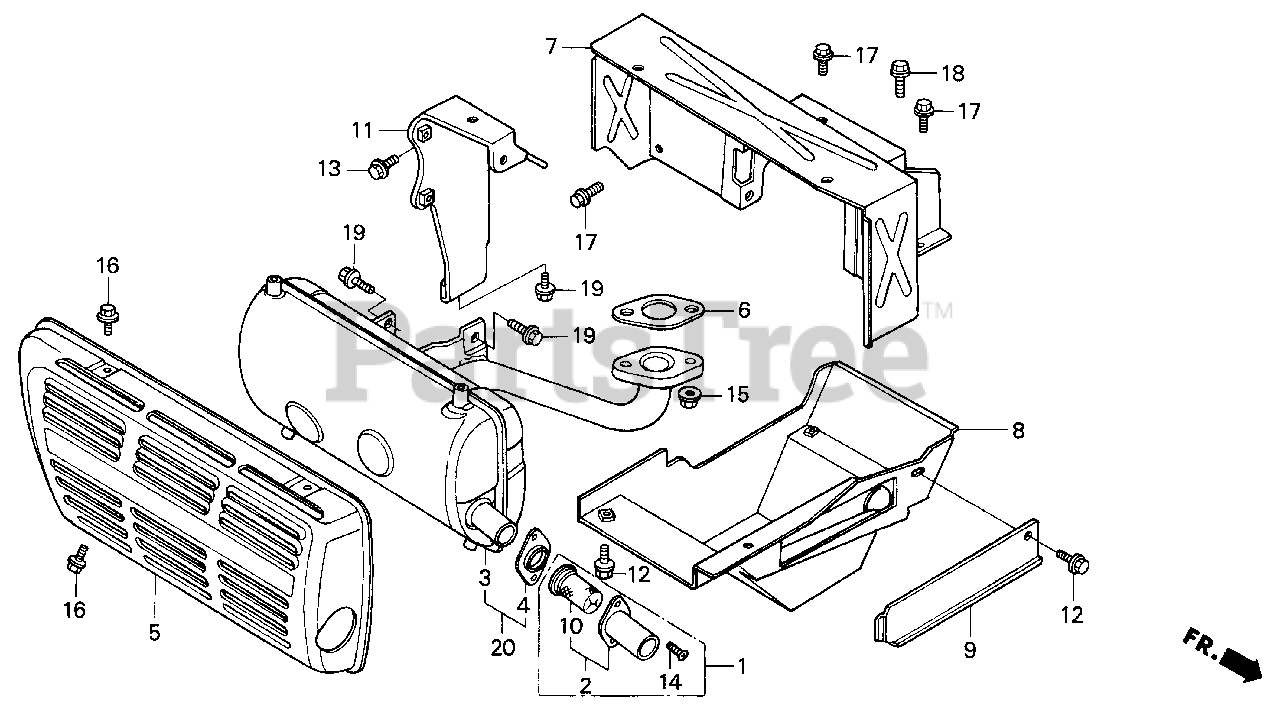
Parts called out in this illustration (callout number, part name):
1	ARRESTER KIT
2	CAP SET, ARRESTER
4	BASE, ARRESTER
5	PROTECTOR, MUFFLER
6	GASKET, EX. PIPE
6	GASKET, EX. PIPE (WACKER)
7	PROTECTOR, HEAT (UPPER)
8	PROTECTOR, HEAT (LOWER)
9	COVER, PROTECTOR (LOWER)
10	ARRESTER, SPARK
11	BRACKET, MUFFLER MOUNTING
12	BOLT, FLANGE (6X12) (CT200)
13	BOLT, FLANGE (8X16)
14	SCREW, PAN (5X8)
15	NUT, FLANGE (8MM)
16	BOLT, FLANGE (6X10)
17	BOLT, FLANGE (6X12)
18	BOLT, FLANGE (8X14)
19	BOLT, FLANGE (8X16)
20	MUFFLER (ARRESTER)
